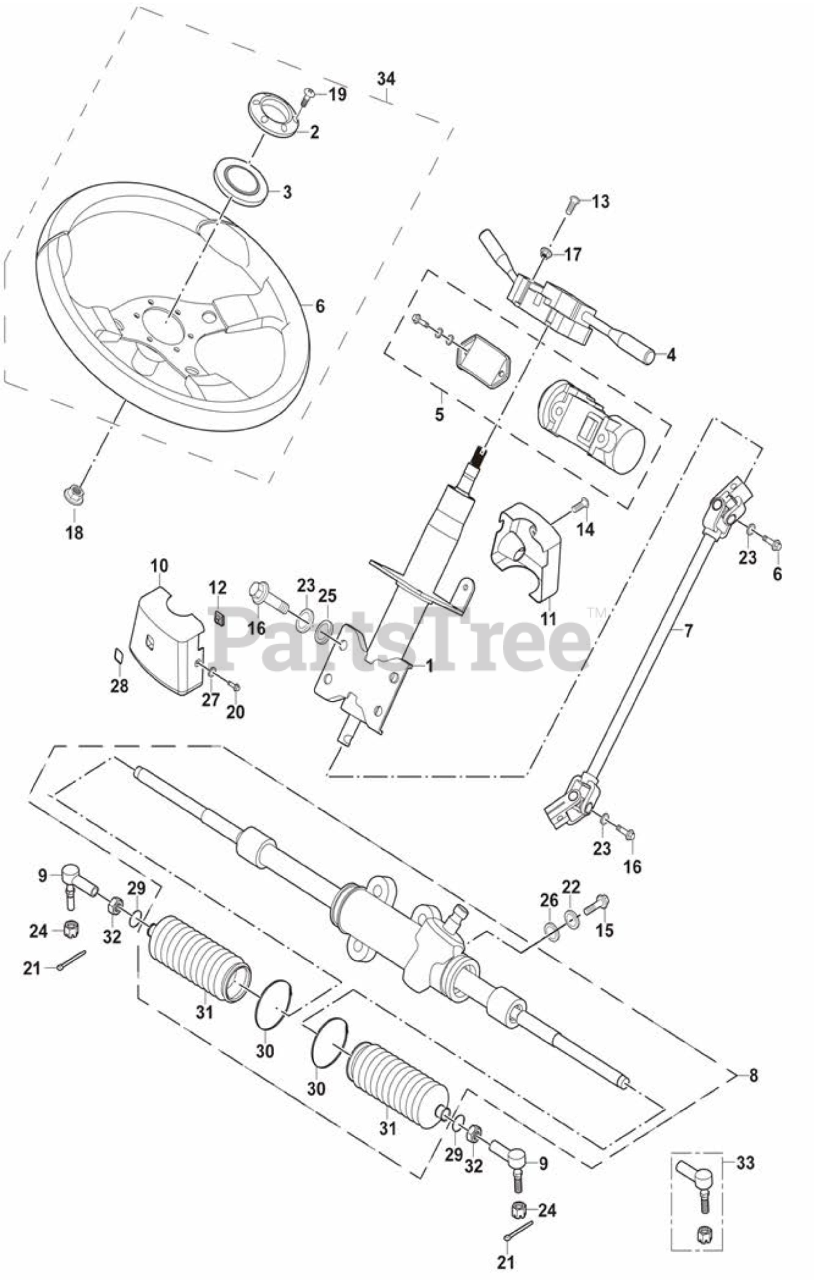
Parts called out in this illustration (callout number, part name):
1	Steering Stem Assy(For E-mark)
2	Decoration Cover For Steering Wheel
3	center cap,steering wheel
4	Cobination Switch
5	Ignition Switch Assy
6	Steering Wheel
7	Drive Shaft Assy
8	Steering Gear Assy
9	Steering Gear Ball Joint
10	Steering Column Cover II
11	Steering Column Cover III
12	Nut Clamp 3.5, Tapping Screw
13	Cross Large Plate Head Screw M5X16
14	Cross Large Plate Head Screw M6X16
15	hexagon flange bolt M10X1.25X35
16	Hexagon Flange BoltM8X25
17	Hexagon Flange nut M5
18	Hexagon Locking Nut M12X1.25
19	Hexagon Socket Bolt
20	Cross Small Plate Head Tapping Screw ST4.8X13
21	Split Pin 2X25
22	Spring Washer10
23	Spring Washer-8
24	hexagon thin slotted nut M12X1.25
26	Flat Washer 10
27	Flat Washer 5
29	Spring Clamp
30	Dirt-proof Boot Clamp
31	Dirt-proof Boot
32	Hexagon Nut M14
33	Steering mechanism Ball joint
34	Steering wheel
